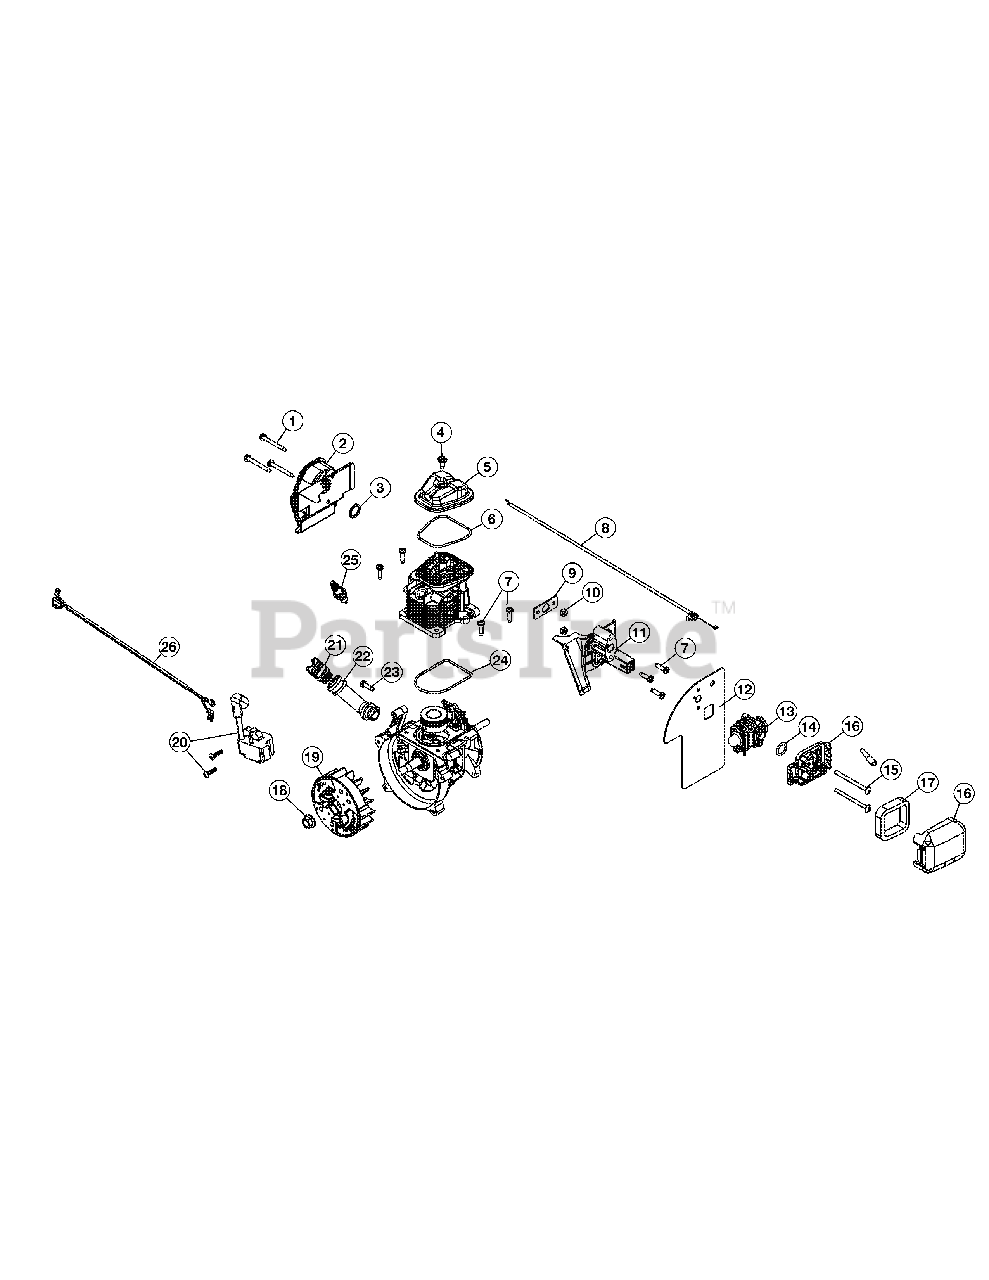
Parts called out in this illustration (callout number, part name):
1	Muffler Screws
2	Muffler Assembly
3	Muffler Gasket
5	Rocker Cover
6	O-Ring
7	Screw
8	Throttle Cable
9	Insulator Gasket
11	Insulator
12	Carburetor Gasket
13	Carburetor
14	Carburetor O-Ring
16	Air Cleaner Assembly
17	Air Filter
19	Flywheel Assembly
20	Module
21	Oil Plug
22	Oil Fill Tube
24	O-Ring
25	Spark Plug
26	Lead Wire
